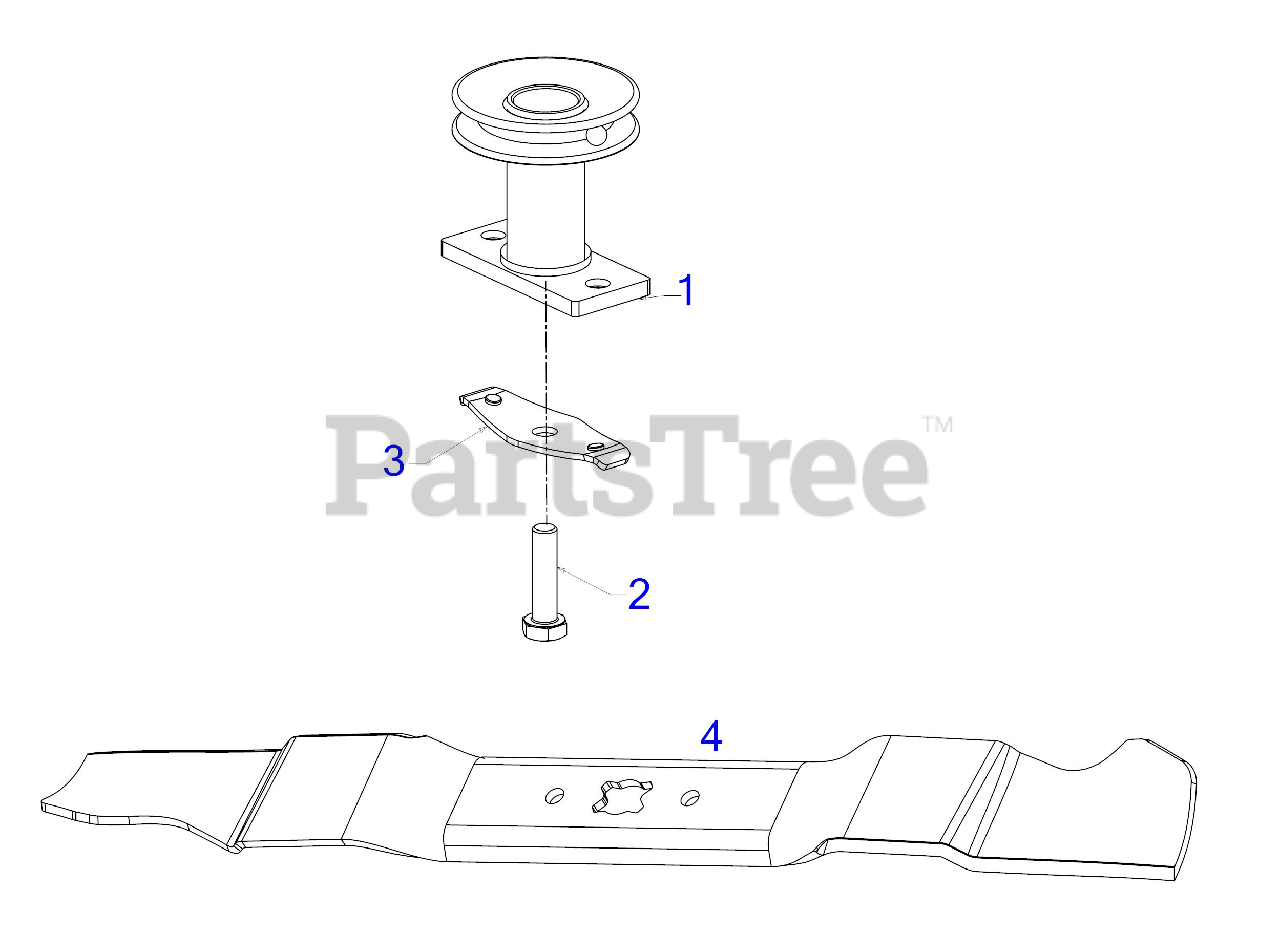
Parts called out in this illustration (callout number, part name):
1	DRIVE PULLEY
2	SCREW 3/8-24 x 1.50 GR8
3	BLADE BELL SUPPORT
4	21" BLADE (MULCH)
4	Cub Cadet 21" MULCH BLADE
4	Genuine Factory Parts 21" MULCH BLADE
4	Genuine Factory Parts 21" MULCHING BLADE (0741A)
4	21" BLADE (MULCH) (XTREME)
